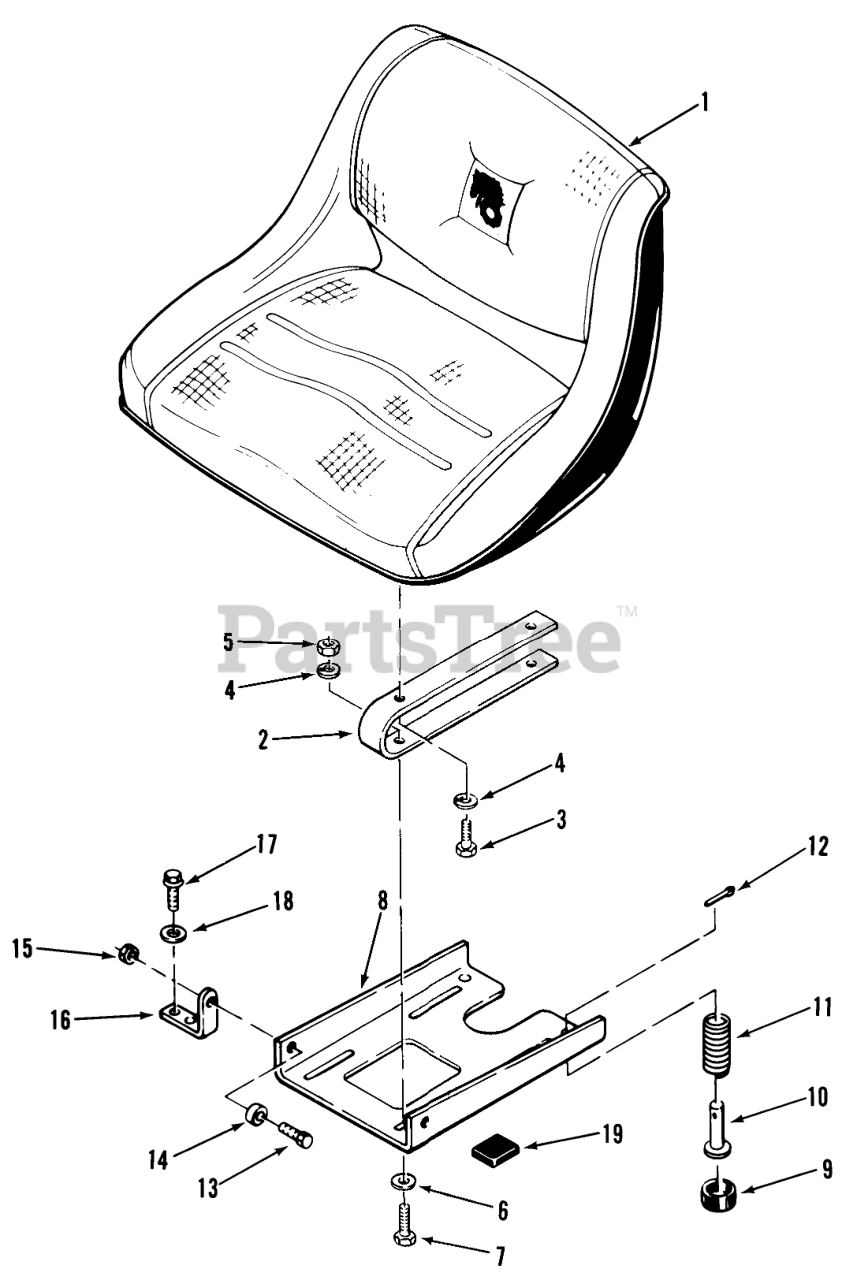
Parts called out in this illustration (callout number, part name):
1	Seat 312, 414
1	Seat
2	Spring
3	Bolt
4	Lockwasher
5	Nut
6	WASHER 5/16 SAE
7	HHCS
8	Pivot Plate
11	SPRING
12	Cotter Pin
13	HHCS
14	BUSHING
15	Nut
16	BRACKET-PIVOT
17	SEAT BOLT FOR C195
18	WASHER 5/16 SAE
19	BUMPER
